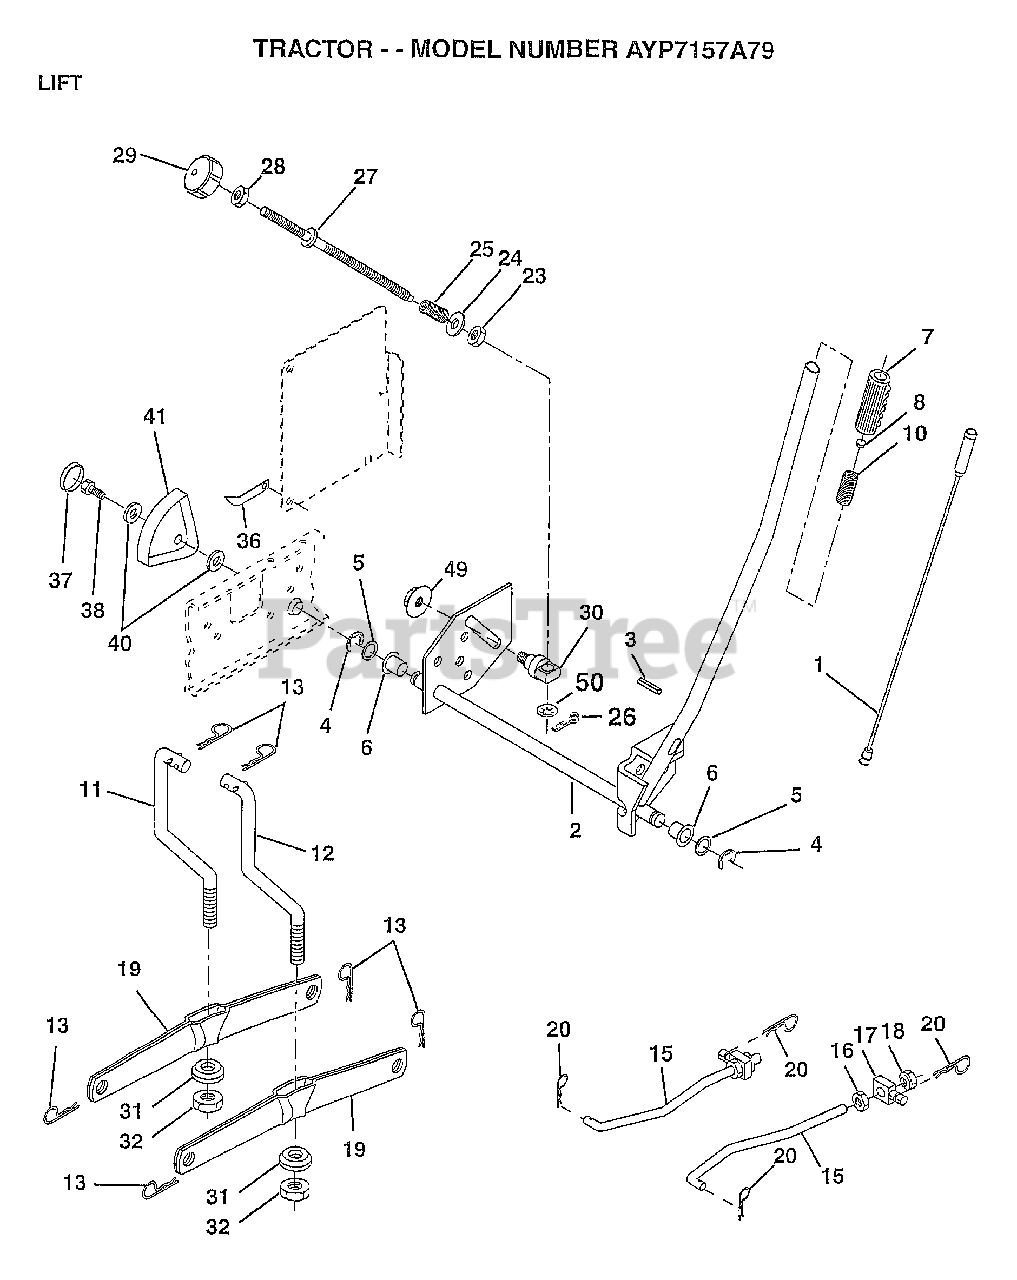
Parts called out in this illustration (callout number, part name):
1	WIRE ASM
2	SHAFT.LIFT.ASM.RH
3	PIN-GROOVE LT
5	WASHER
5	NYLON BEARING
7	GRIP HANDLE
15	LINK.FRONT
16	NUT
17	TRUNION
18	NUT.LK.W/WSH.1/2.
19	ARM SUSP REAR
20	RETAINER.SPRING
23	NUT T
24	WASHER
25	SPRING T
28	NUT
29	KNOB INF 3/8-16
30	TRUNNION
31	BEARING PVT LH
32	NUT.CROWNLOCK.3/8
36	POINTER-INDICAT
37	"PLUG,HOLE"
38	SCREW
40	WASHER
41	HEIGHT INDICATOR
49	NUT.HXFLG.LOCK.
